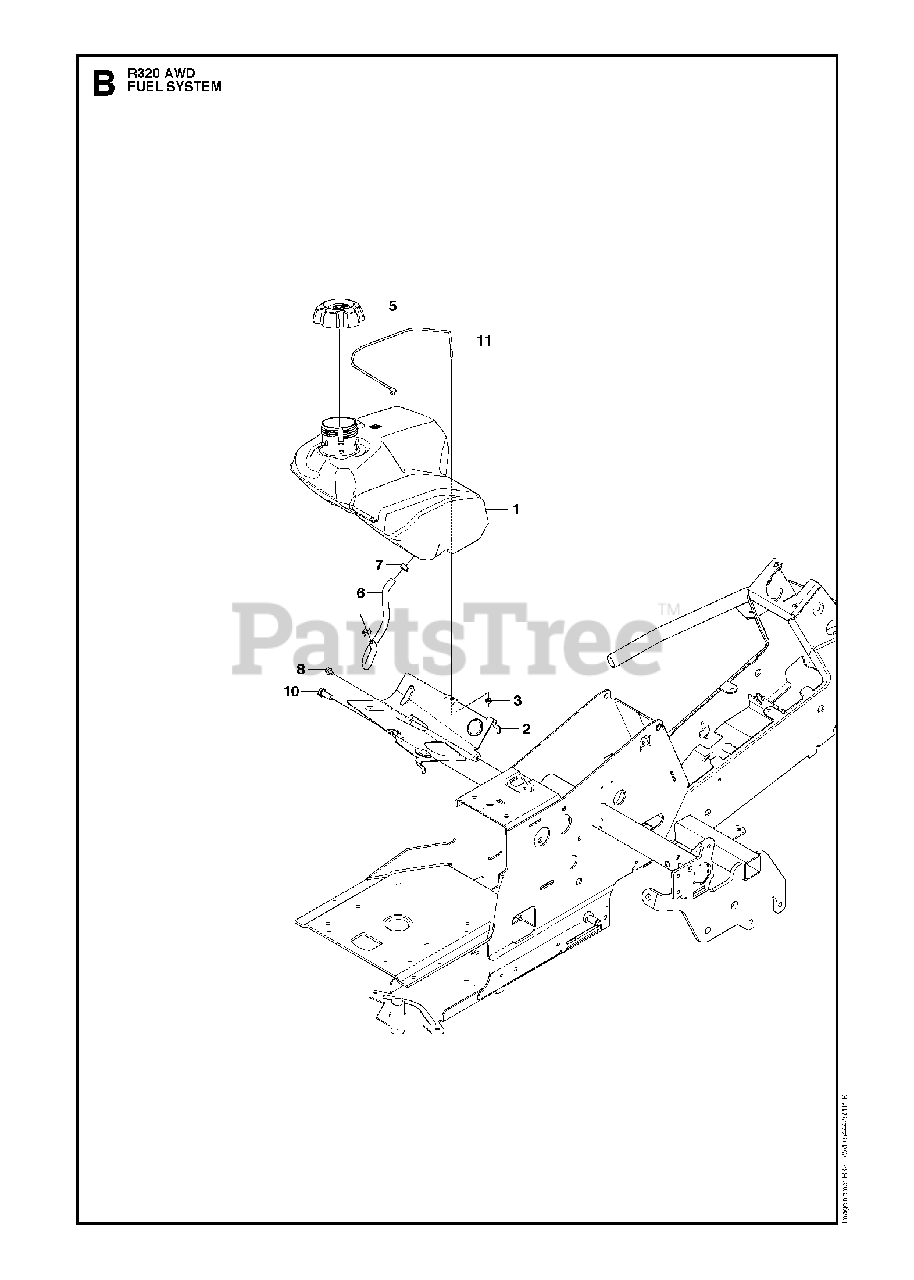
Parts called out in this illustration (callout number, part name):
3	LOCKNUT M6
5	CAP.FL.R.3'N/CARB.H.CROWN.498
10	Screw, M10 X 25
